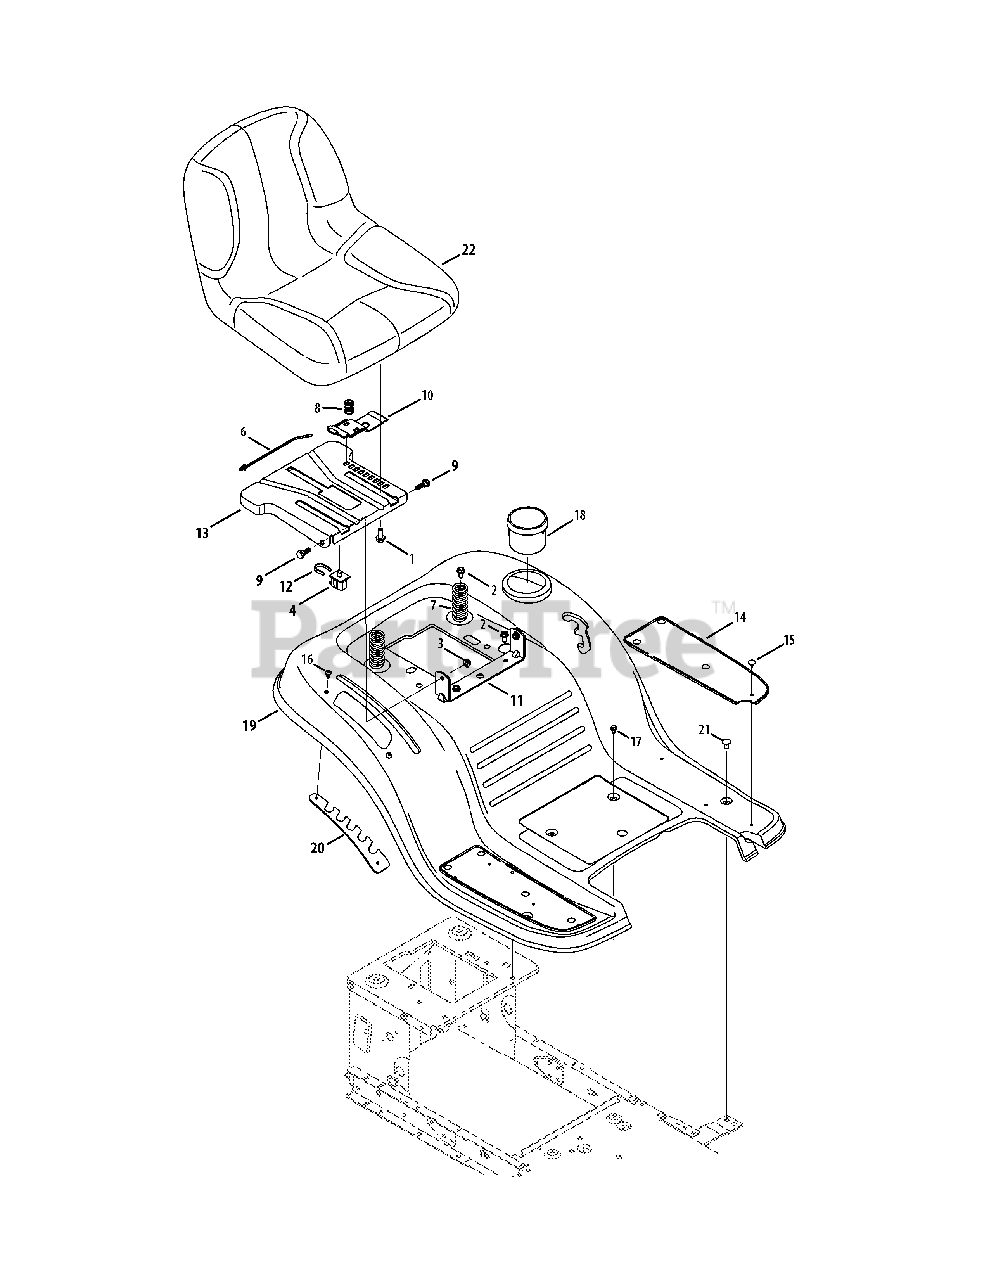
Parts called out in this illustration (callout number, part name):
1	Hex Flange Bolt, 3/8-16 x .875
2	Screw, Hd. Tapp, 5/16-18 x .75
3	Flange Lock Nut, 5/16-18
4	Seat Safety Switch
6	Push Mount Cable Tie
7	Spring, Compress., 1.28 x 3.125
8	Spring, Compress., .68 x 1.065 x .055
9	Shoulder Screw, 5/16-18 x .437 x .268
10	Seat Adjustment Lever
11	Seat Pivot Bracket
12	Switch Retainer Clip
14	Rubber Foot Pad, LH
14	Rubber Foot Pad, RH
15	Ratchet Clip, .250
16	Tap Screw, 1/4-20 x .5
17	Screw Pan Torx Head, 1/4-20 x .500
18	Cup Holder
19	Fender
20	Lift Adjuster Bracket
21	Carriage Screw, 1/4-20 x .62
22	Seat
